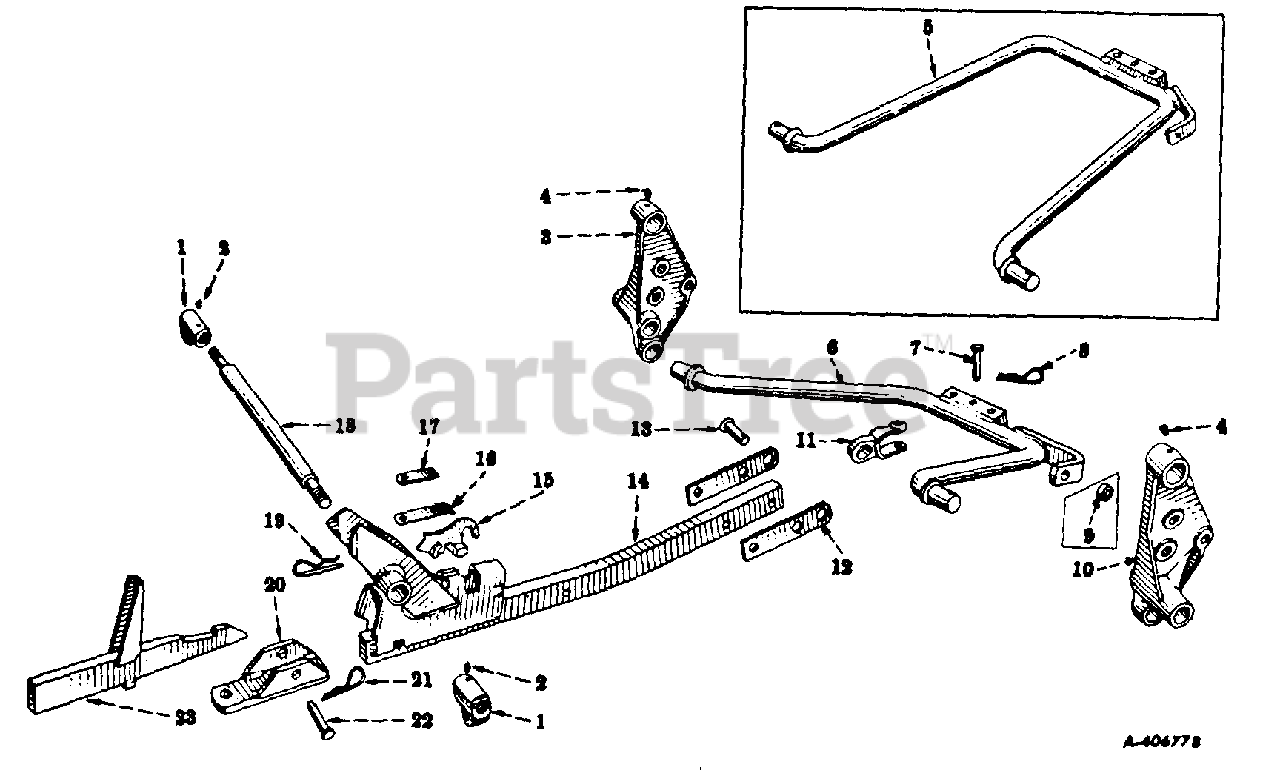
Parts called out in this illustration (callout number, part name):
1	SWIVEL, LATERAL LINK LOWER
2	FITTING, 1/8-27 STR LUB
3	BRACKET, HITCH ATTACHING LH
4	FITTING, 1/8 X 67-1/2 DEG ELBOW LUB
5	BAIL ASSY, HITCH
6	BAIL ASSY, HITCH
7	PIN, PULL BAR PIVOT BRACKET
8	PIN, 3/16 QUICK-ATTACHABLE COT.
10	BRACKET, HITCH ATTACHING RH
11	BRACKET, PULL ROD PIVOT
12	STRAP, PULL BAR EXTENSION
13	PIN, PULL BAR PIVOT
14	BAR ASSY, PULL
15	LATCH, PULL BAR
16	SPRING, LATCH
17	SPRING, AUXILIARY LATCH
18	SUPPORT, PULL BAR
19	PIN ASSY, QUICK-ATTACHABLE COT.
20	EXTENSION, PULL BAR
21	PIN, 3/16 QUICK-ATTACHABLE COT.
22	PIN, 5/8 X 3-5/16 STD-HD DRILLED
23	COUPLING, BEAM
